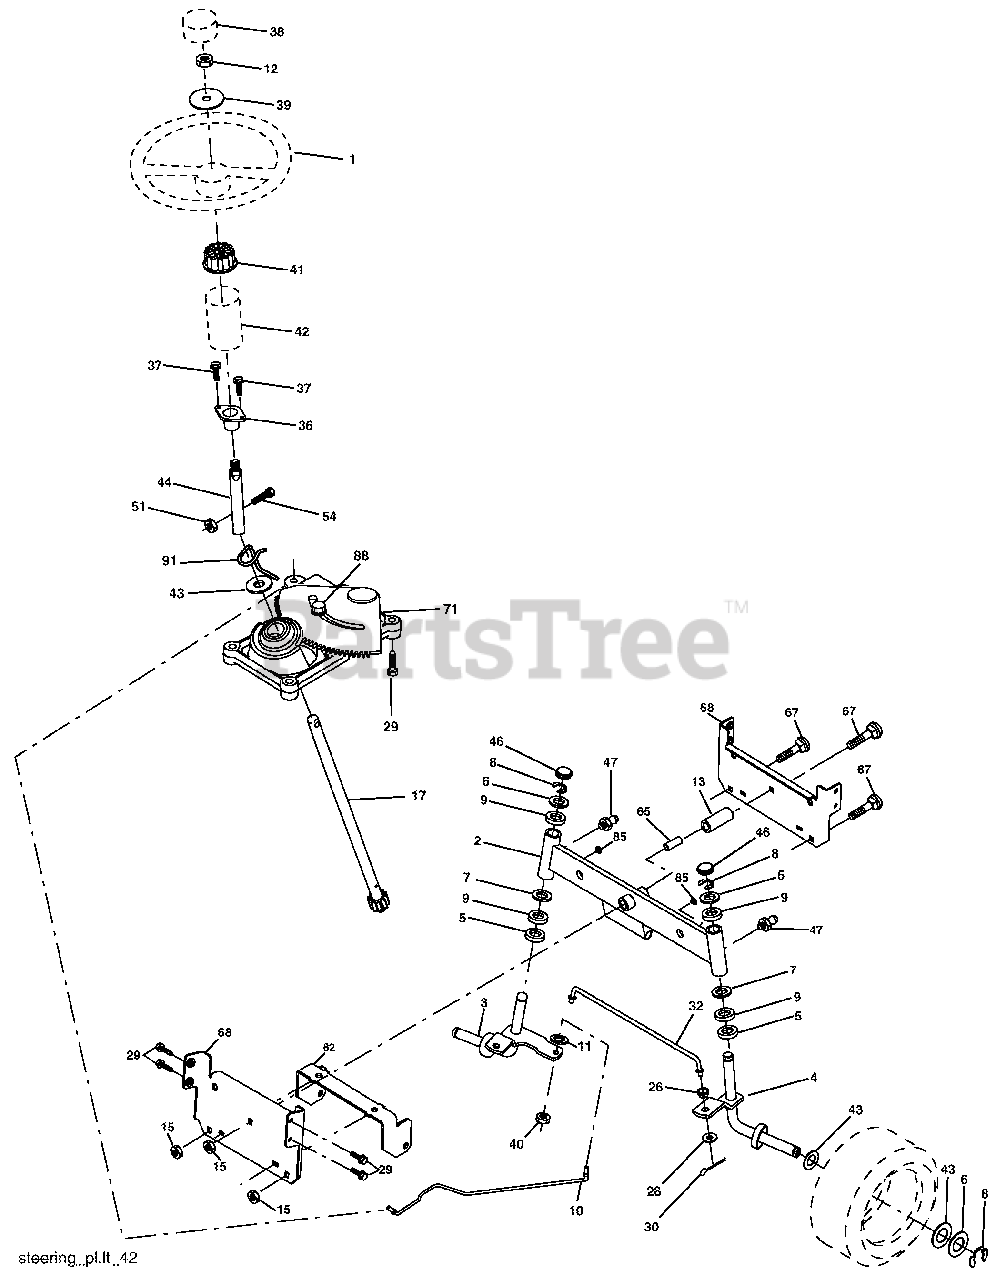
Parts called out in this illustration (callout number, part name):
1	Wheel Steering Auto Black
2	Axle Asm Front
3	Spindle Asm Lh
4	Spindle Asm Rh
5	Bearing Race Thrust Harden
6	Washer 25/32 x 1 5/8 x 16ga
7	Washer 27/32 x 1 1/4 x 16 Ga
8	Ring Klip #t5304-75
9	Bearing Col Strg Blk
10	Link Drag Extended
11	Lockwasher
12	Nut Hex Jam Toplock 1/2-20 Unf
13	Spacer Bearing Axle Front
15	Hex Flange Lock
17	Shaft Asm Strg
26	Bushing Rod Tie Blk Lt
28	Washer 13/32 x 7/8 x 16ga
29	Screw 3/8-16 x 3/4
30	Pin
32	Rod Tie Wire Form 19 75 Mech
36	Bushing Strg 5/8 Id Dash
37	Screw TT #10-32 x 5 x 3/8 Flange
38	Insert Cap Strg
39	Washer 9/16 ID x 2-3/8 OD 12 Gr
40	Locknut Center
41	Adaptor Wheel Strg
42	Boot Dash Steering
43	Washer 25/32 x 1 1/4 x 16 Ga
44	Extension Steering
46	Cap Spindle Fr Top Blk
47	Fitting Grease
51	Nut Crownlock 1/4-28
54	Bolt Hex 1/4-28 Unf x 1-1/4 Gr. 8
65	Spacer Brace Axle
67	Bolt Rdhd Sq 3/8-16 Unc x 2-3/4
68	Brace Axle
71	Steering Asm
82	Bracket Susp Chassis Front
85	Fastener Christmas Tree
88	Bolt Shoulder 7/16-20
91	Clip Steering
